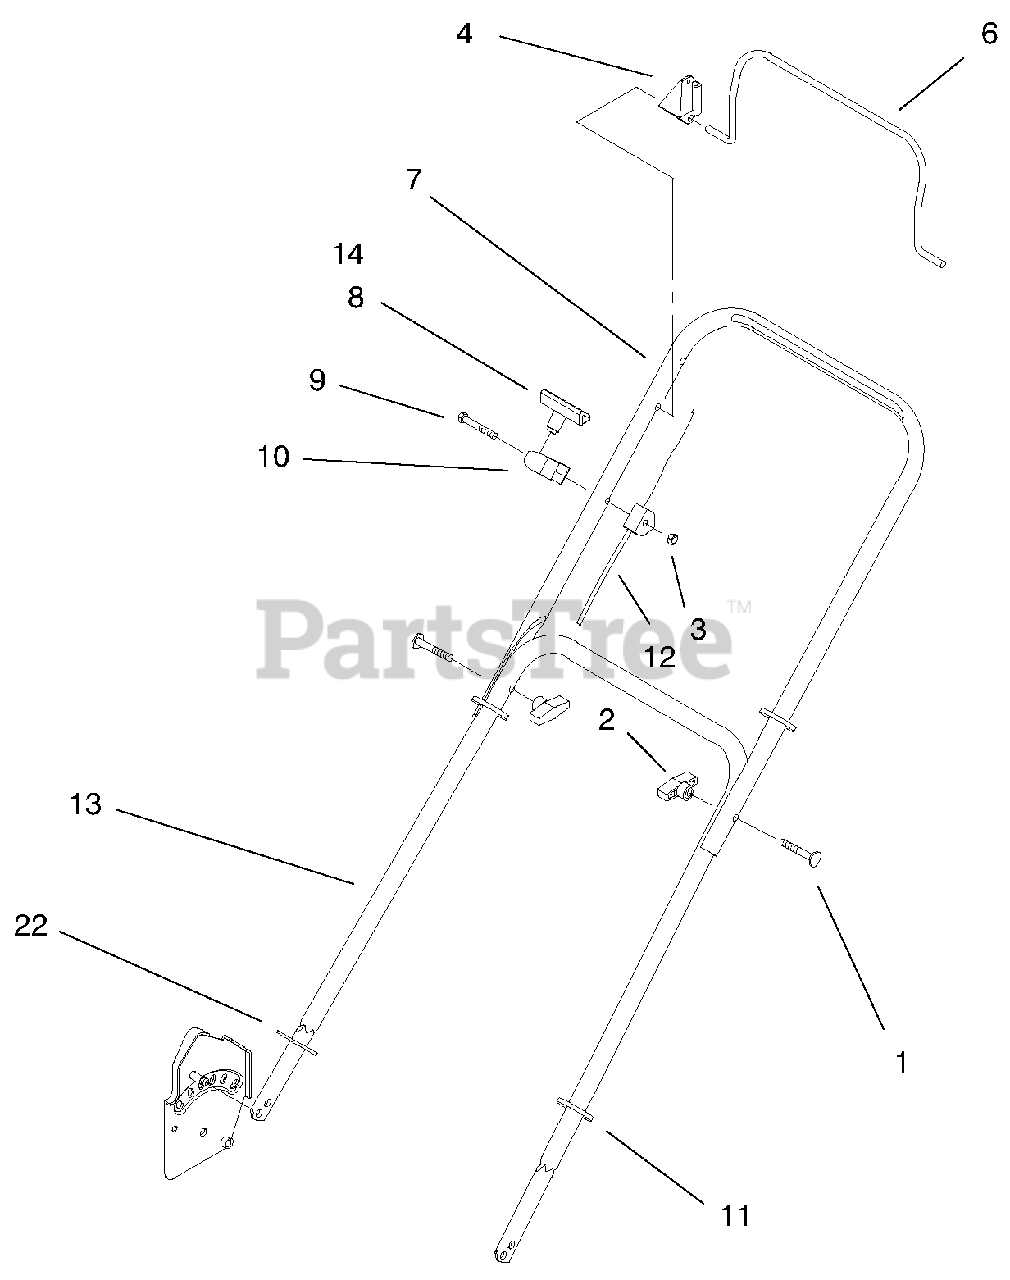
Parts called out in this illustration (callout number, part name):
1	Screw-Handle
3	Nut-Lock
4	Stop-Pivot
6	Bail-Flywheel Brake
7	Handle Section-Upper
8	Handle-Starter
10	Guide-Rope
11	Tie Strap
12	ASM-Brake Cable
13	Handle Section-Lower
14	Staple-Handle
22	Handle-Guard
